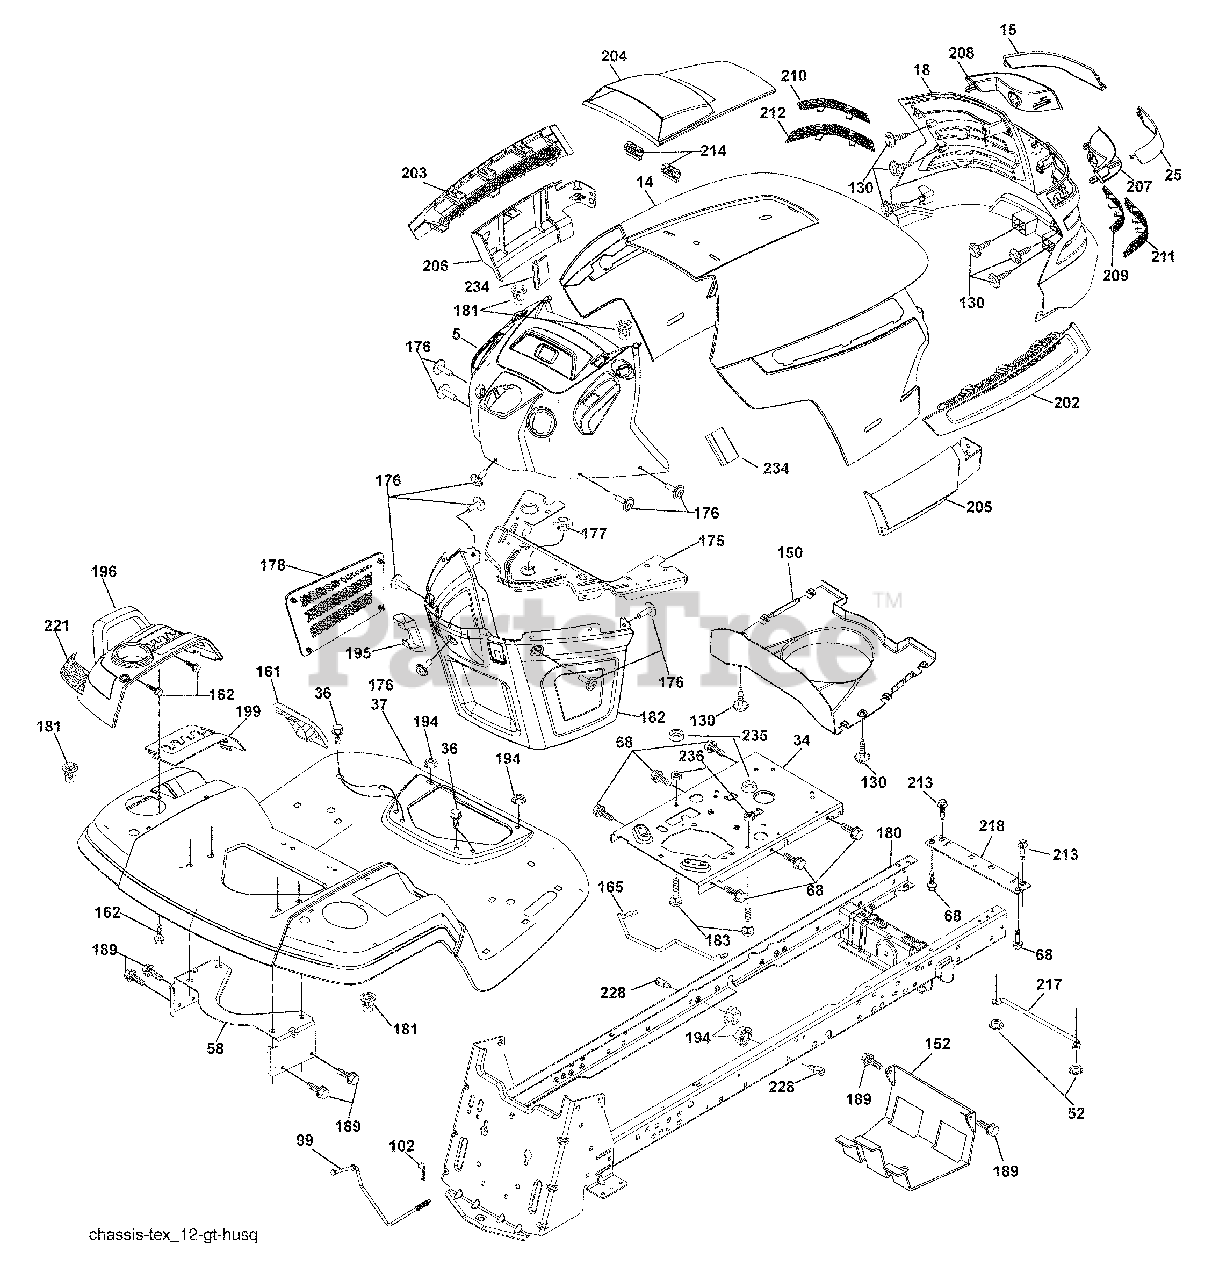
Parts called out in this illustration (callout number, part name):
14	Hood
18	Grille
34	Plate Engine
36	Screw 5/16-18 x 3/4
37	Fender
52	Nut Crown Lock 5/16-18
58	Bracket Fender
68	Screw 5/16-18 x 1/2
99	Rod Bypass Asm.
130	Screw 10 x 3/4 Single Lead Hex
150	Duct Heat Hood
152	Shield Browning/Debris
161	Console Fuel Window
162	Screw Hex Wsh Hi-Lo 1/4 x 1/2
165	Bracket Support Tank
175	Crossmember
176	Screw 10-24 x 5/8 Wshd Qdrx
177	Bushing Steering
178	Cargo Asm. Net
180	Chassis
181	Bushing Mtg. Fender Crgo.
182	Dash Lower
184	Spacer Fender
185	Bolt Fin Hex 5/16-18 unc x 1-1/4
189	Screw 5/16-18 x 3/4
194	Nut Lock Hex Flange 5/16-18
195	Plug Cruise/Phone
196	Console Asm. Deck Lift
199	Plate Deck Lift
202	Vent Side Hood RH
203	Vent Side Hood LH
204	Vent Asm Hood Top
205	Skirt Hood Side RH
206	Skirt Hood Side LH
209	Insert Hex Top RH
210	Insert Hex Top LH
211	Insert Hex Bottom RH
212	Insert Hex Bottom LH
213	Bolt Hex Hd 5/16-18 unc x 3/4
214	Clip Retainer
217	Rod Pivot
221	Refl ector LH
228	Stud Fastener
234	Bumper Hood
236	Nut Center Lock 5/16-18 UNC
